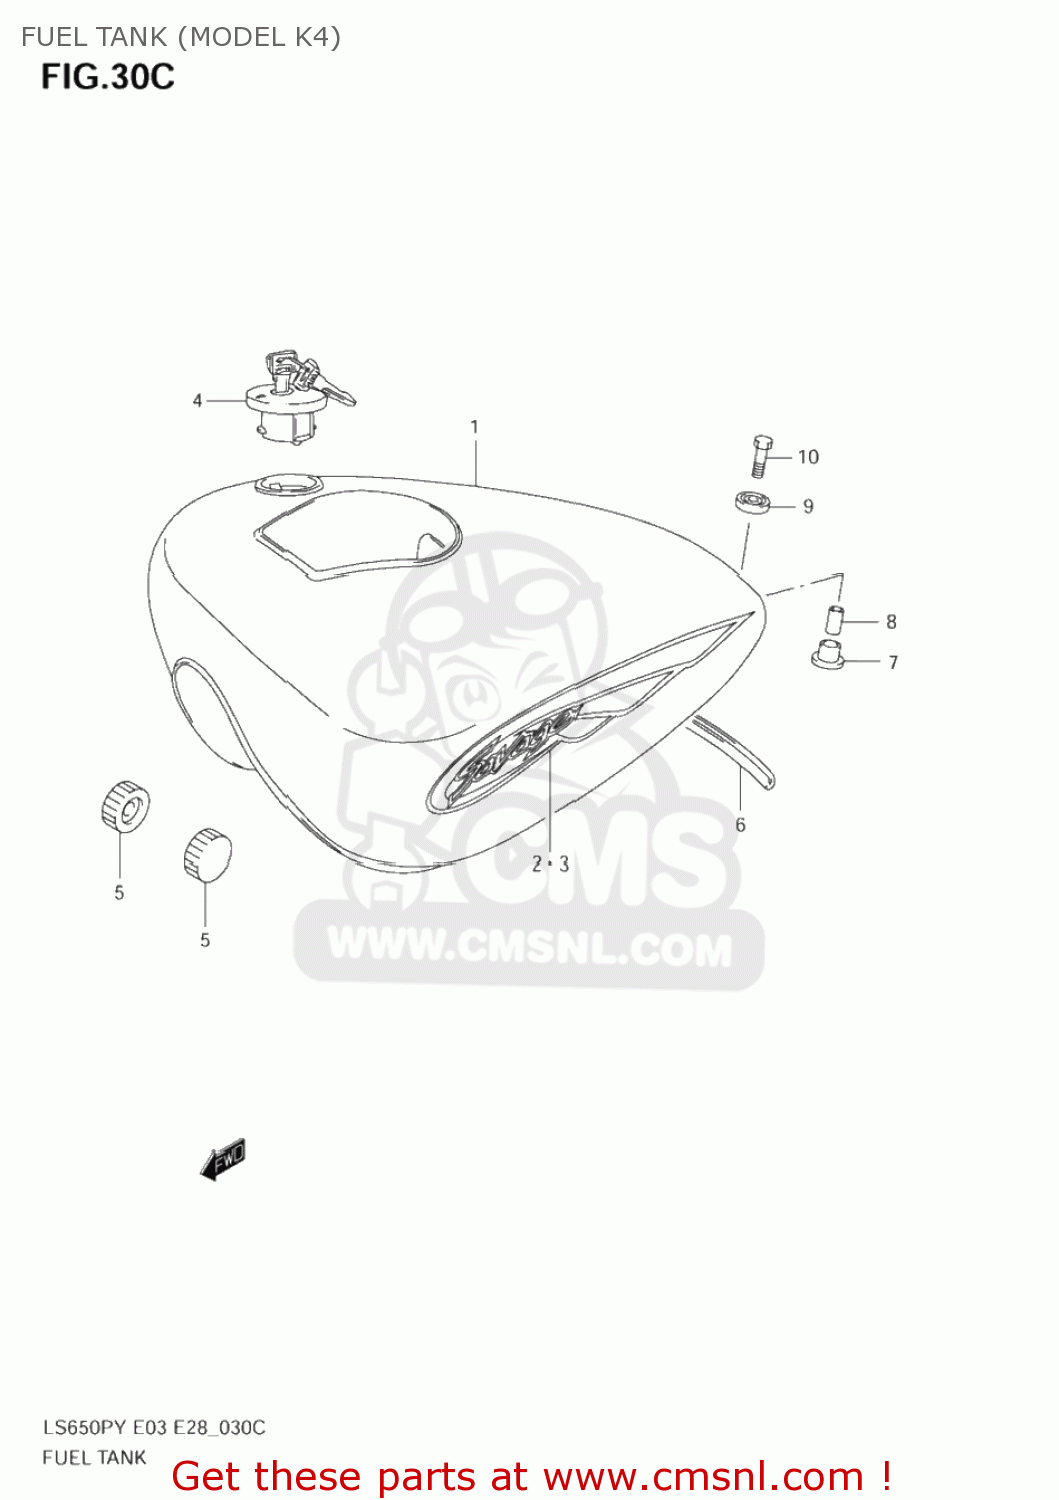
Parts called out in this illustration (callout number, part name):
1	TANK ASSY,FUEL(SILVER)
2	EMBLEM,FUEL TANK,R(BLACK)
3	EMBLEM,FUEL TANK,L(BLACK)
4	CAP SET,FUEL TANK
5	CUSHION
6	MOLDING,FUEL TANK RR
7	CUSHION
8	SPACER(6.5X9X18)
9	CUSHION
10	BOLT
